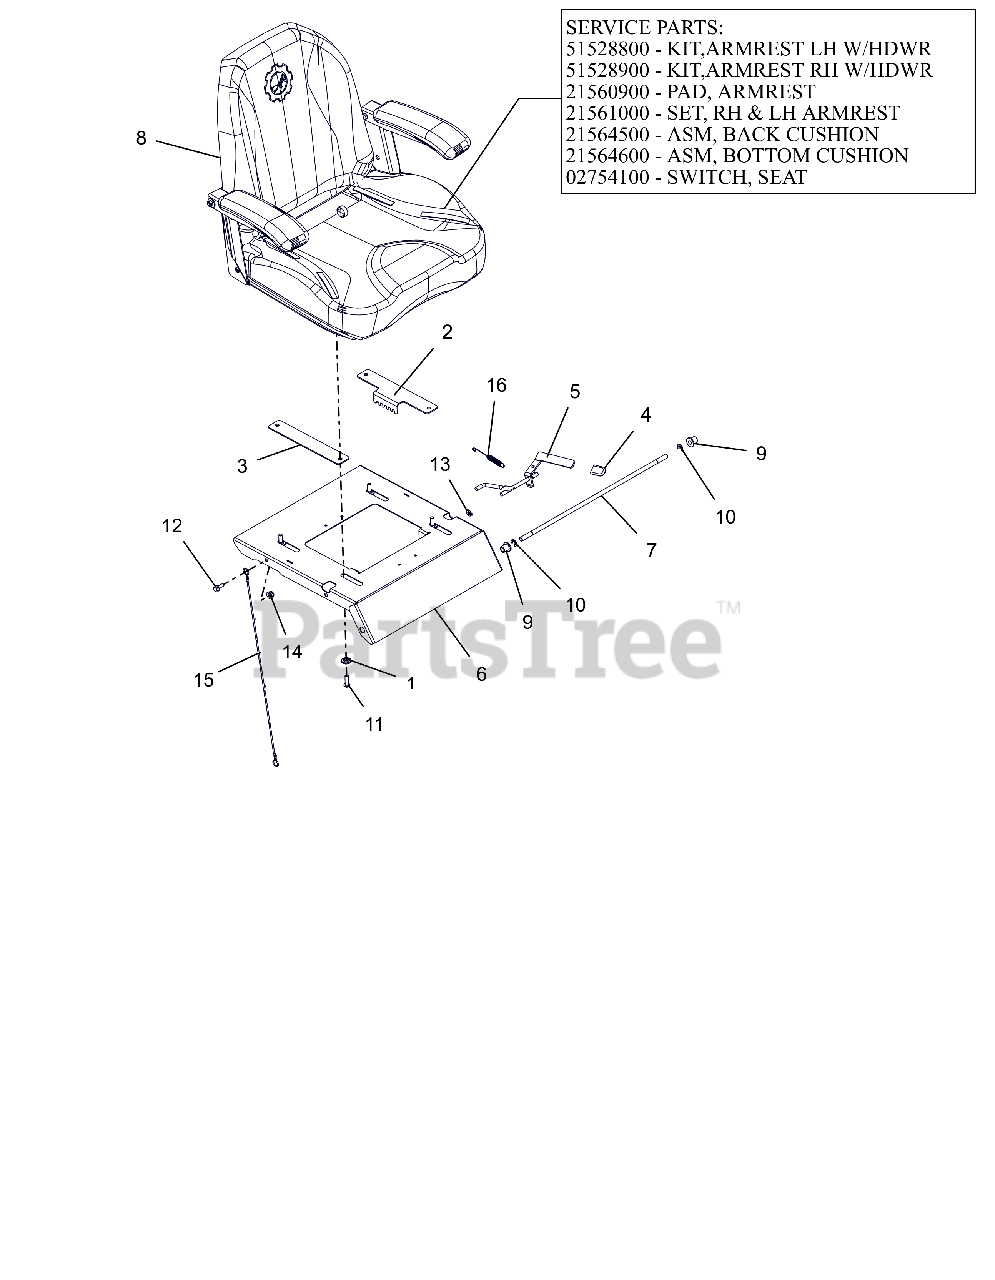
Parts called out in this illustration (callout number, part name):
1	BSHG, FLG .325X.499X.26X.88
2	PLATE, ADJUSTABLE SEAT TRACK
3	PLATE, ADJUSTABLE SEAT SLIDE
4	GRIP, SEAT LEVER, GREY
5	WLDMT, ADJUSTABLE SEAT LATCH
6	PLATE, SEAT
7	ROD, SEAT PIVOT
8	SEAT, IKON
8	KIT, ARMREST LH
8	KIT, ARMREST RH
8	PAD, ARMREST (HARD)
8	SET,RH & LH ARMREST -HARD
8	ASM, BACK CUSHION-ARIENS X
8	ASM, BOTTOM CUSHION-ARIENS X
8	SWITCH- SNAP MTG N.O.
9	BSHG-FLG .38X.580X.667X.750
10	RG-RTNG-EXT .375X.035 TYP E
11	SCR-SKH .31-18X1.0 BTNHD YWZC
12	BLT,HEX-FLG .25-20X.75 G5 BFP
13	NUT-PUSH .312
14	@NUT-LK-NYL-FLG .31-18 YWZC
15	LANYARD, SEAT CABLE .093X19.5
16	SG-TENS .043X.44X3.31 WLD 5.8
